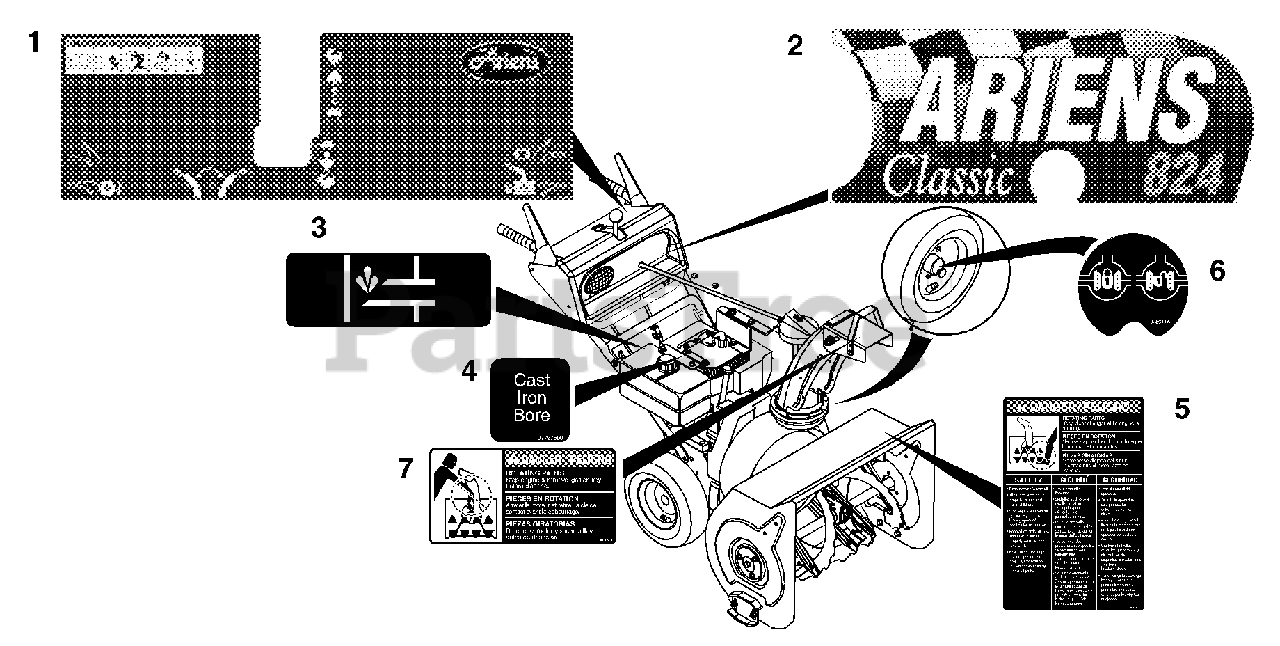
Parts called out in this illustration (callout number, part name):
1	DECAL- CONTROL
2	DECAL- FRONT PANEL 824 CLASSIC
3	DECAL, PRIMER "TECUMSEH'S"
4	DECAL - CAST IRON BORE
5	DECAL, DANGER
6	DIFFERENTIAL LOCK DECAL
7	DECAL, DANGER - ROT. PARTS
